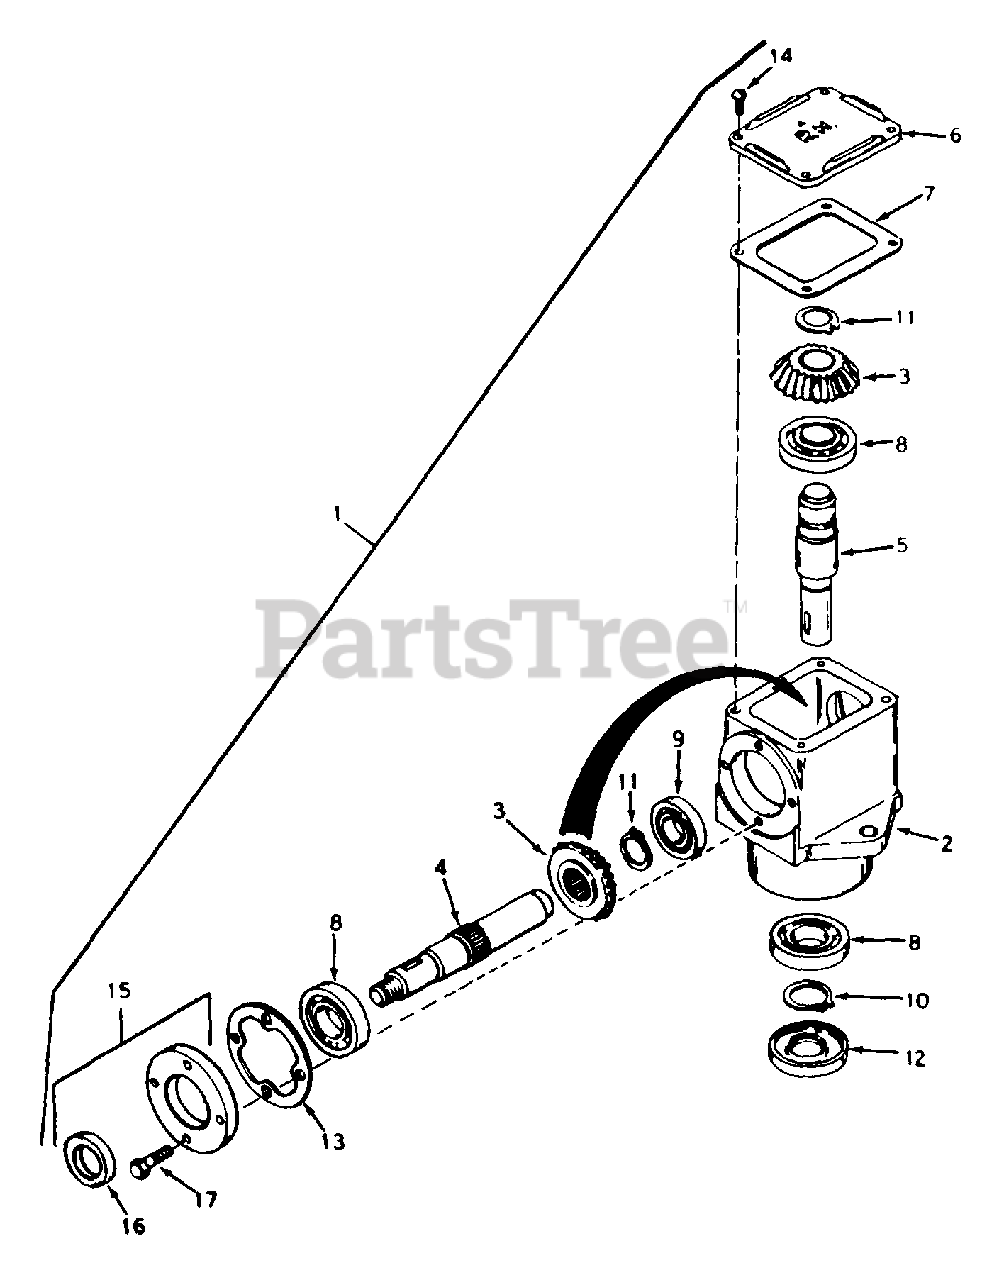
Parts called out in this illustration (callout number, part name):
1	Head Ass'y. R.H.
2	Housing, Right Angle Drive
3	Gear, Miter
4	Shaft, Input
5	Shaft, Output
6	Cover, Right Hand
7	Gasket, Cover
8	Bearing, Ball
9	Bearing, Ball
10	Ring, Snap
11	Ring, Snap
12	Seal, Oil
13	Gasket, Cap
14	Screw, Rd. Hd. Self-Tap. 10-24 x 1/2
15	Cap & Seal Ass'y., Retainer
16	Seal, Oil
17	Screw, Hex Hd. 1/4-20 x 7/8
